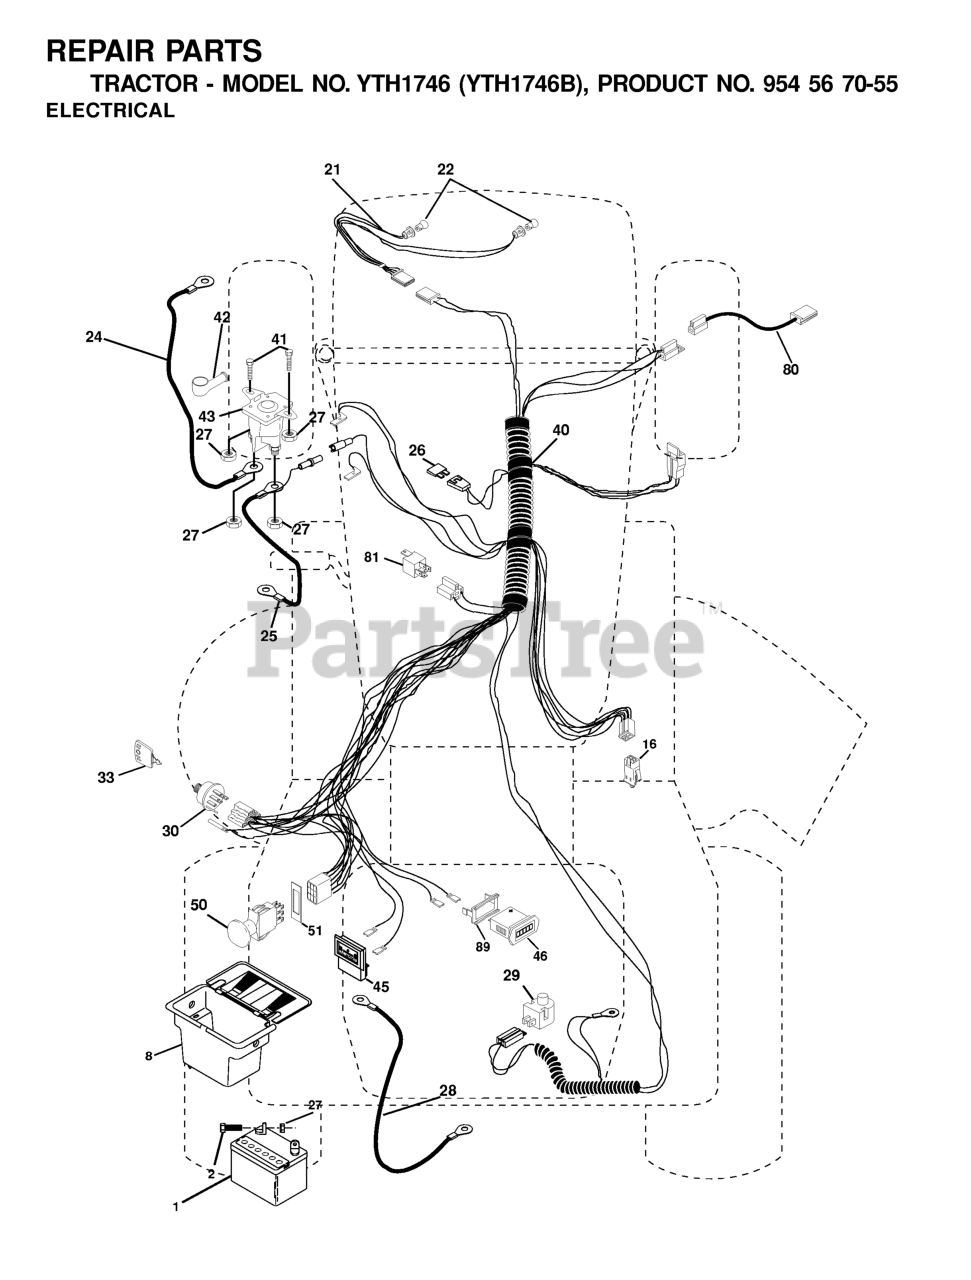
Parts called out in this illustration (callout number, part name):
1	BATTERY 12 VOLT 25 AMP
2	BOLT.HEX.1/4.X.3/4.DICHROMATE
8	CASE BATTERY MECH HINGE
16	SWITCH INTERLOCK
24	BATTERY CABLE GT
25	CABLE BATTERY
26	FUSE 20AMP
27	NUT
28	CABLE T
29	PLUNGER SWITCH (COLOR:OLIVE)
30	IGNITION SWITCH
33	KEY MLD GEN DELTA
40	HARNESS IGN.
41	BOLT
42	TERMINAL COVER
43	REPL BY 532 1461-54
46	HOUR METER
50	RP.PTO.SWITCH.8 TERMINAL.BLACK
51	FRAME RETAINING RING
80	HARNESS, CLUTCH
81	RELAY.ASSY.T
89	BRACKET SNAP-IN HOURMETER
